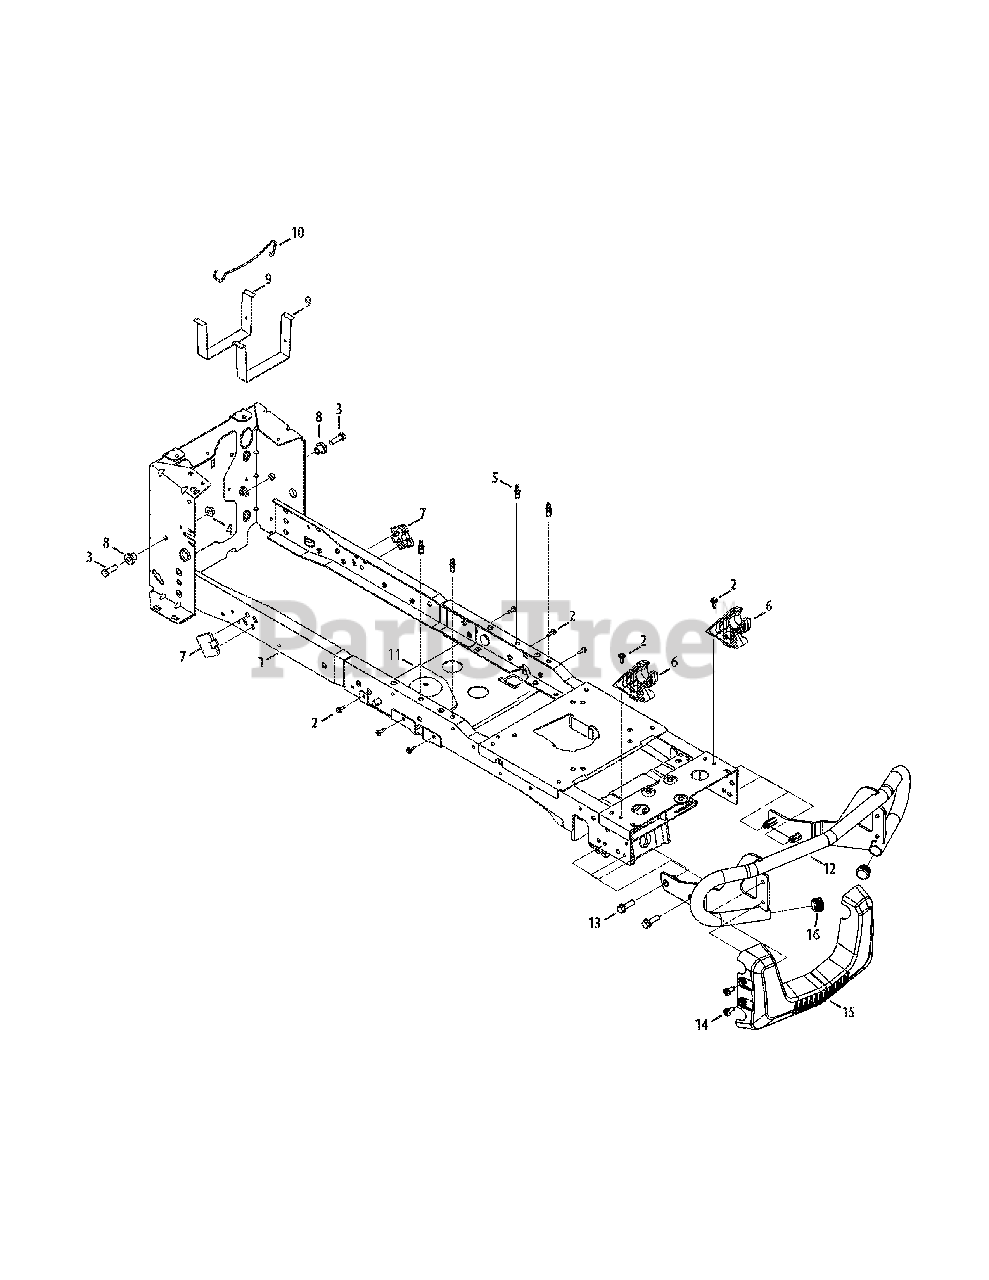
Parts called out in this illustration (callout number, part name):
1	Frame Assembly
2	Screw, M6-1 x .625
3	Hex Cap Screw, 3/8-16 x 1.25
4	Flange Lock Nut, 3/8-16
5	Rivet, 1/4-20 x .750
6	Pivot Bracket
7	Wear Pad
8	Shoulder Spacer, .38 x 1.0 x .70
9	Battery Bracket
10	Rod, Battery
12	Bumper Assenbly
13	Hex Flange Screw, 3/8-16
14	Self Tapping Screw, 5/16-18 x .75
15	Bumper
16	Hub Cap
